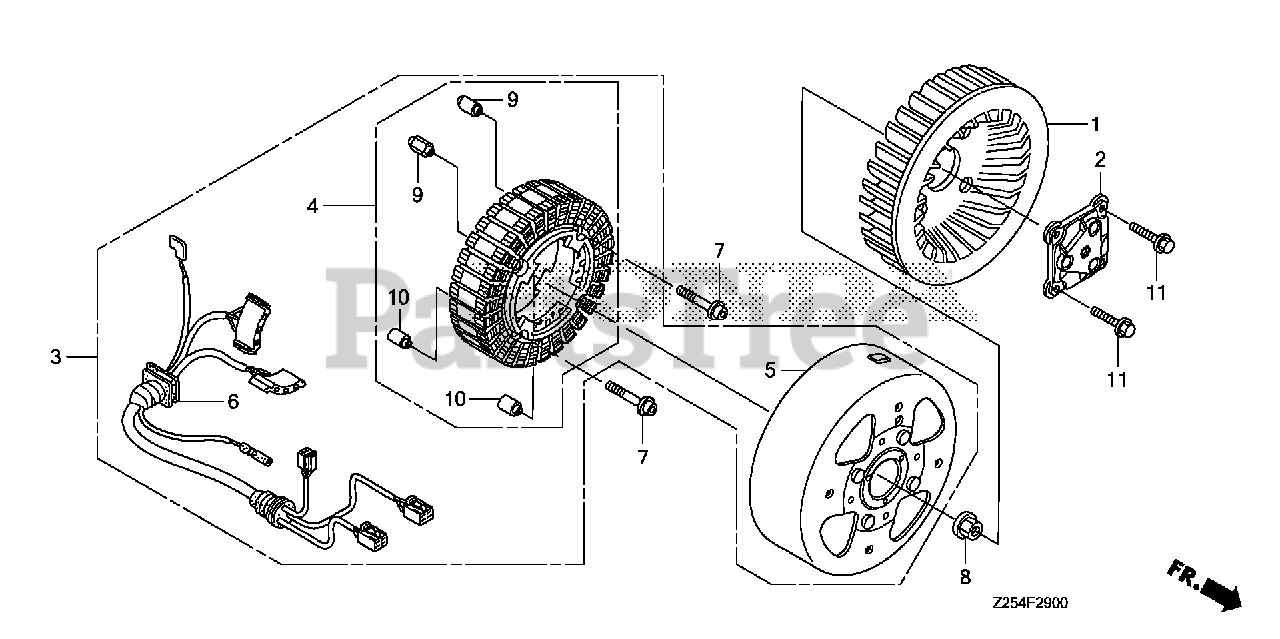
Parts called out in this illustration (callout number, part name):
1	FAN, COOLING
2	ADAPTER, RECOIL PULLEY
3	GENERATOR ASSY.
4	CORE SET, STATOR COIL
6	WIRE HARNESS ASSY., GENERATOR
7	BOLT, FLANGE SOCKET (6X78) (CT200)
8	NUT, SPECIAL (16MM)
9	COLLAR, STATOR (6.3X13X21.5)
10	COLLAR, STATOR (6.3X13X16.5)
11	BOLT, FLANGE (6X25)
